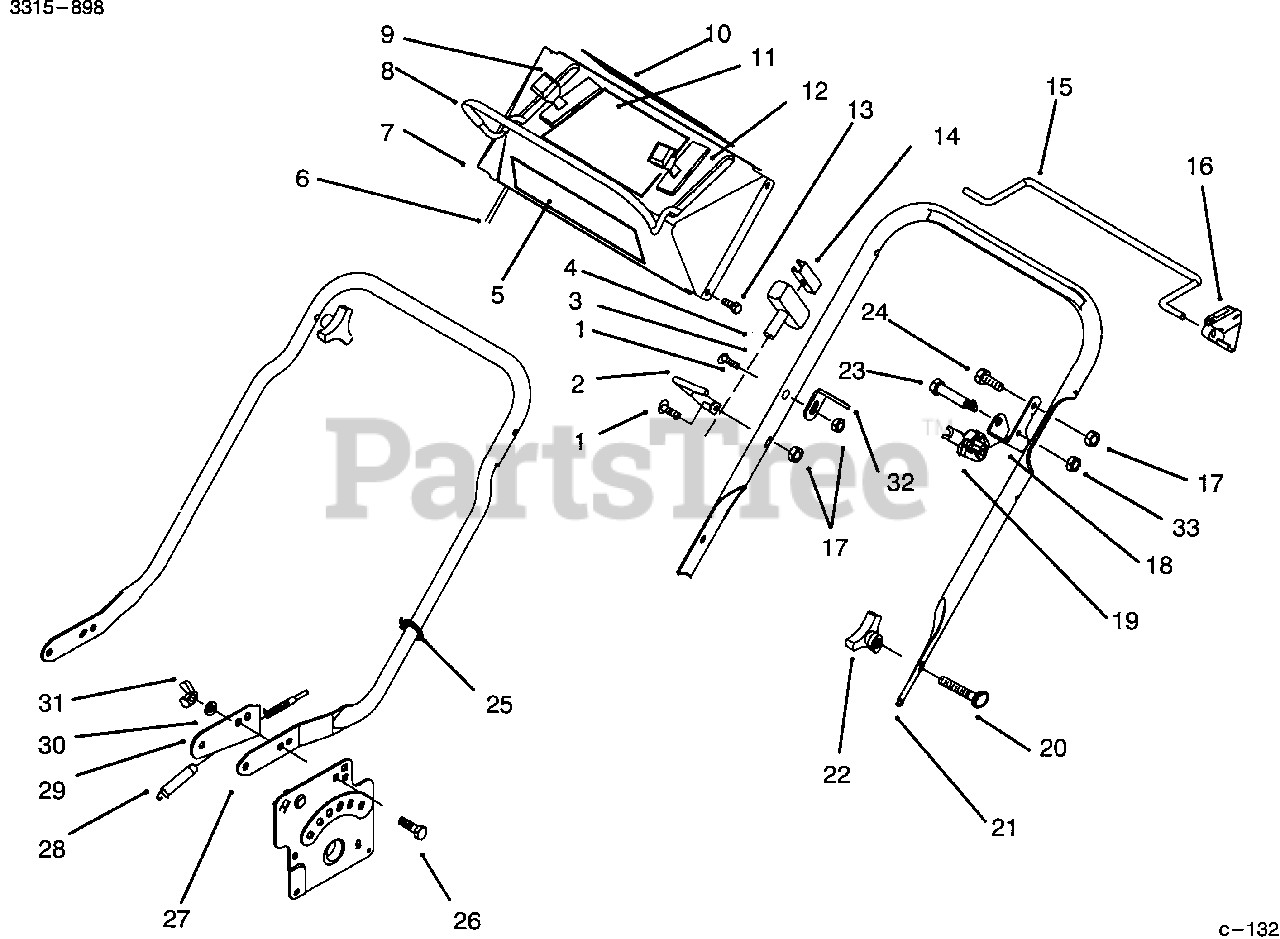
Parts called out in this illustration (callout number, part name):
2	Guide-Rope
3	Rope-Starter
4	Handle-Rope
5	Decal-Control Panel
6	Cable-Brake
7	Panel-Control (Incl. Ref. #10 & 11)
8	Bail-BBC Brake
9	Control Ground (Self Propelled)
10	Decal-Warning (English)
11	Decal-Control Panel, (Self Propelled English)
12	Control-Throttle
13	Screw
14	Insert-Handle
15	Bail-Control, (Self Propelled)
16	Stop-Pivot (Self Propelled)
18	Bracket-Cam
19	Brake-BBC Cam
20	Screw-Handle
21	Handle-Upper
22	Knob-Handle
23	Bolt-Shoulder
24	Screw-Hex. Hd.
25	Tie-Cable
26	Bolt-Carriage
27	Handle-Lower
28	Cable-Traction (Self Propelled)
29	Bracket-Traction Cable (Self Propelled)
32	Bracket-Cable
